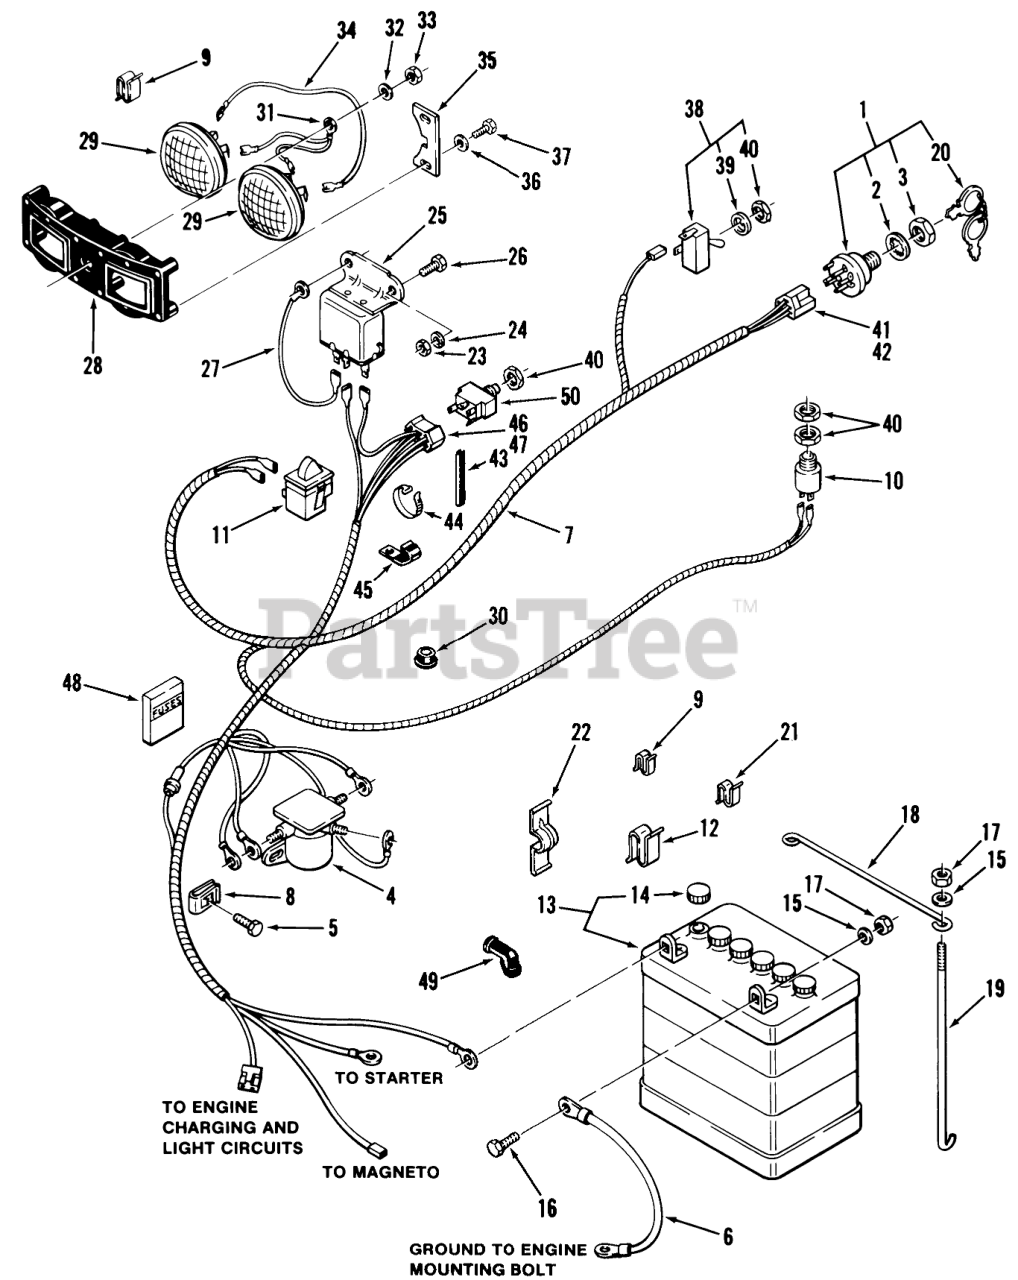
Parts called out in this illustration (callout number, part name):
1	SWITCH-IGNITION
2	LOCKWASHER
3	884 Special Nut
4	SOLENOID
5	HEX WASHER HD SCREW
6	Wire
7	ASSY-WIRING HARNESS
7	ASSY-WIRE HARNESS
8	Speed Nut
9	SPEED CLIP
10	SWITCH
11	SWITCH INTERLOCK
12	Clip
13	Battery
16	Bolt
17	Nut
18	ROD-HOLD DOWN
19	Hook
20	Key-EL
21	SPEED CLIP
22	Clip "Stick-On"
23	Nut
24	Lockwasher
25	Relay
26	Bolt 10-32 X 5/8
27	RELAY-GROUND WIRE
28	Headlight Retainer
29	HEADLAMP
30	BUSHING-NYLON .75
31	LIGHT GROUND WIRE
32	WASHER 5/16 SAE
33	Nut
34	WIRE-HEADLIGHTS
35	Clamp
37	SCREW
38	SWITCH-LIGHTS
39	TAB-WASHER
40	NUT-HEX
41	CONNECTOR-5 WAY-SERV
42	SWITCH ASSY
43	EDGE TRIM 4IN OF 102896
44	Cable Tie
45	CLIP
46	CONNECTOR 5 WAY
47	Terminal
49	Terminal Cover
50	SWITCH-CLUTCH
